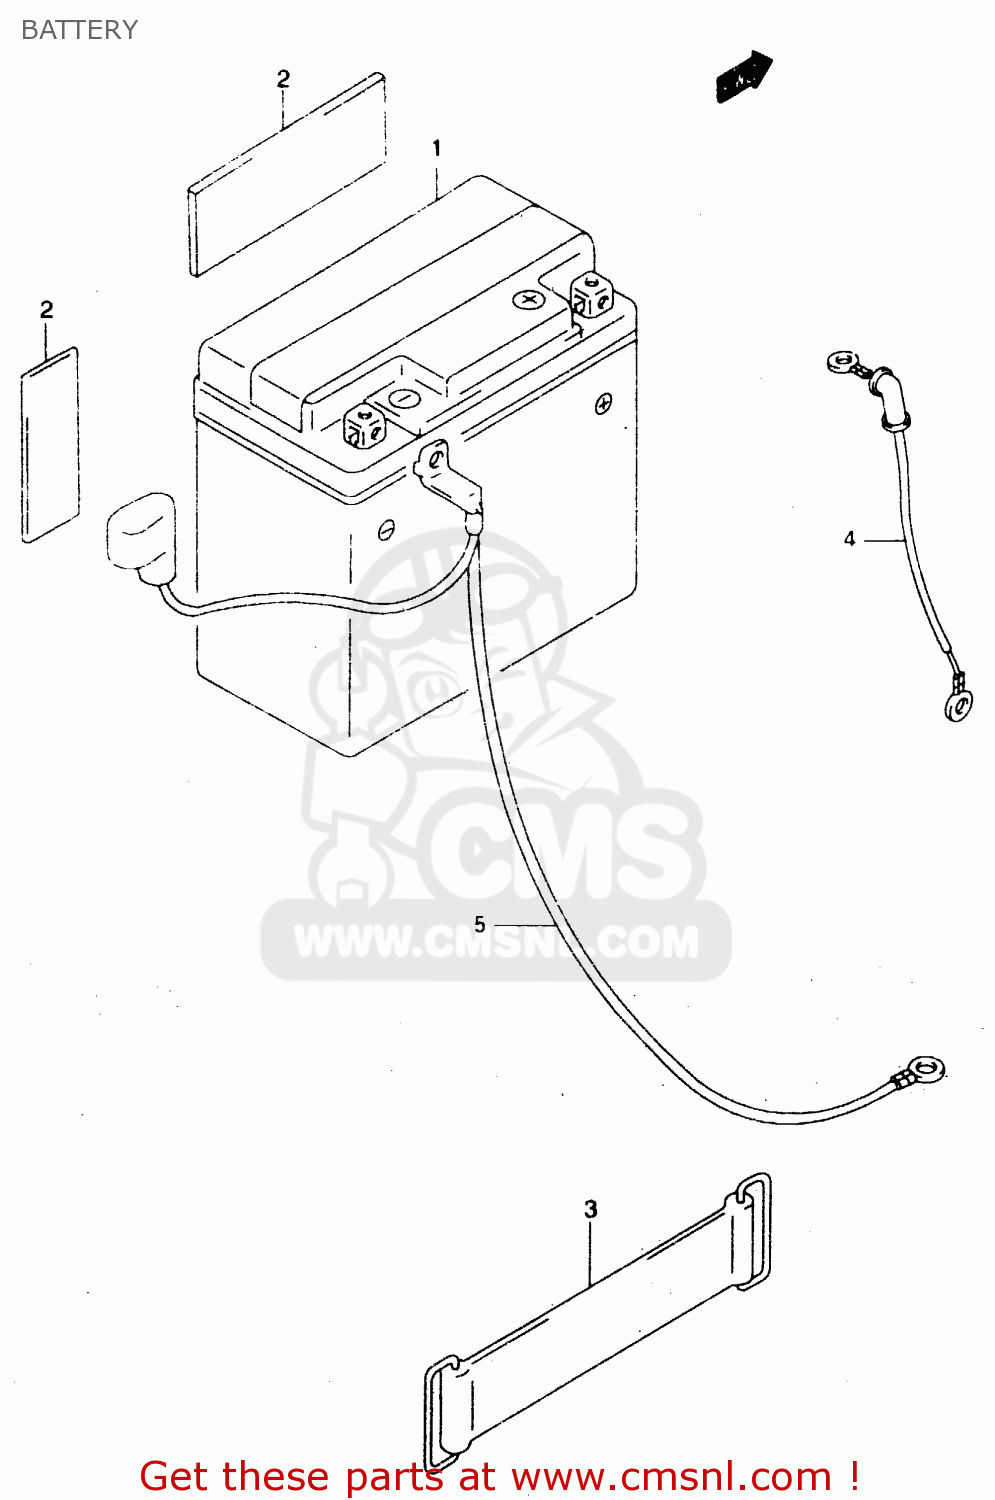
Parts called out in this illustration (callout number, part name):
1	BATTERY ASSEMBLY (12V) FTX
2	PROTECTOR(170X95X3.0)
3	BAND
4	WIRE,BATTERY PLUS LEAD
5	WIRE,BATTERY MINUS
